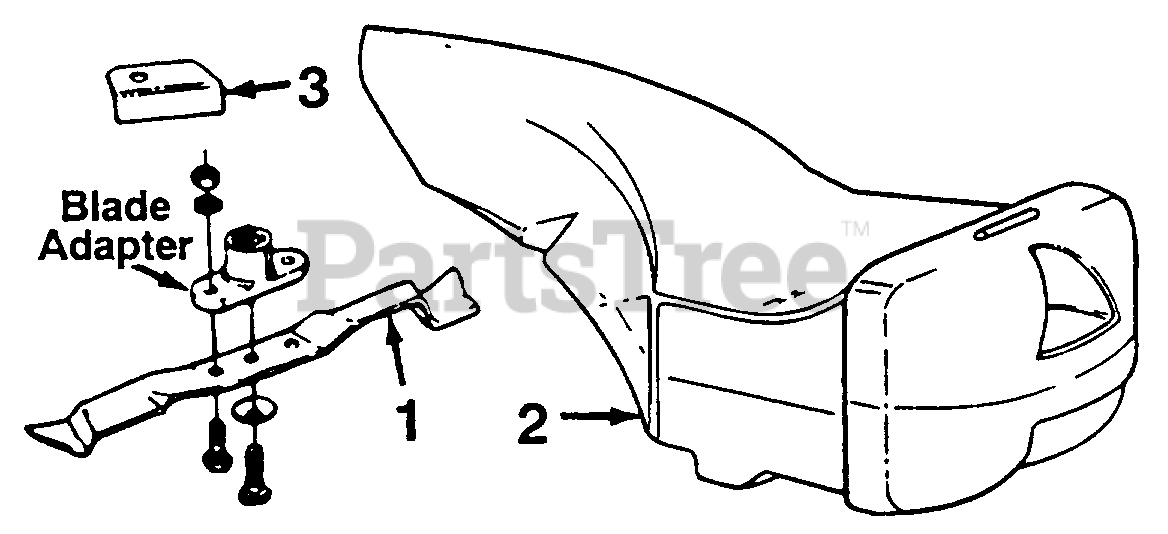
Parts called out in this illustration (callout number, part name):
1	Mulching Blade
2	Mulching Plug
3	Stop Bracket
